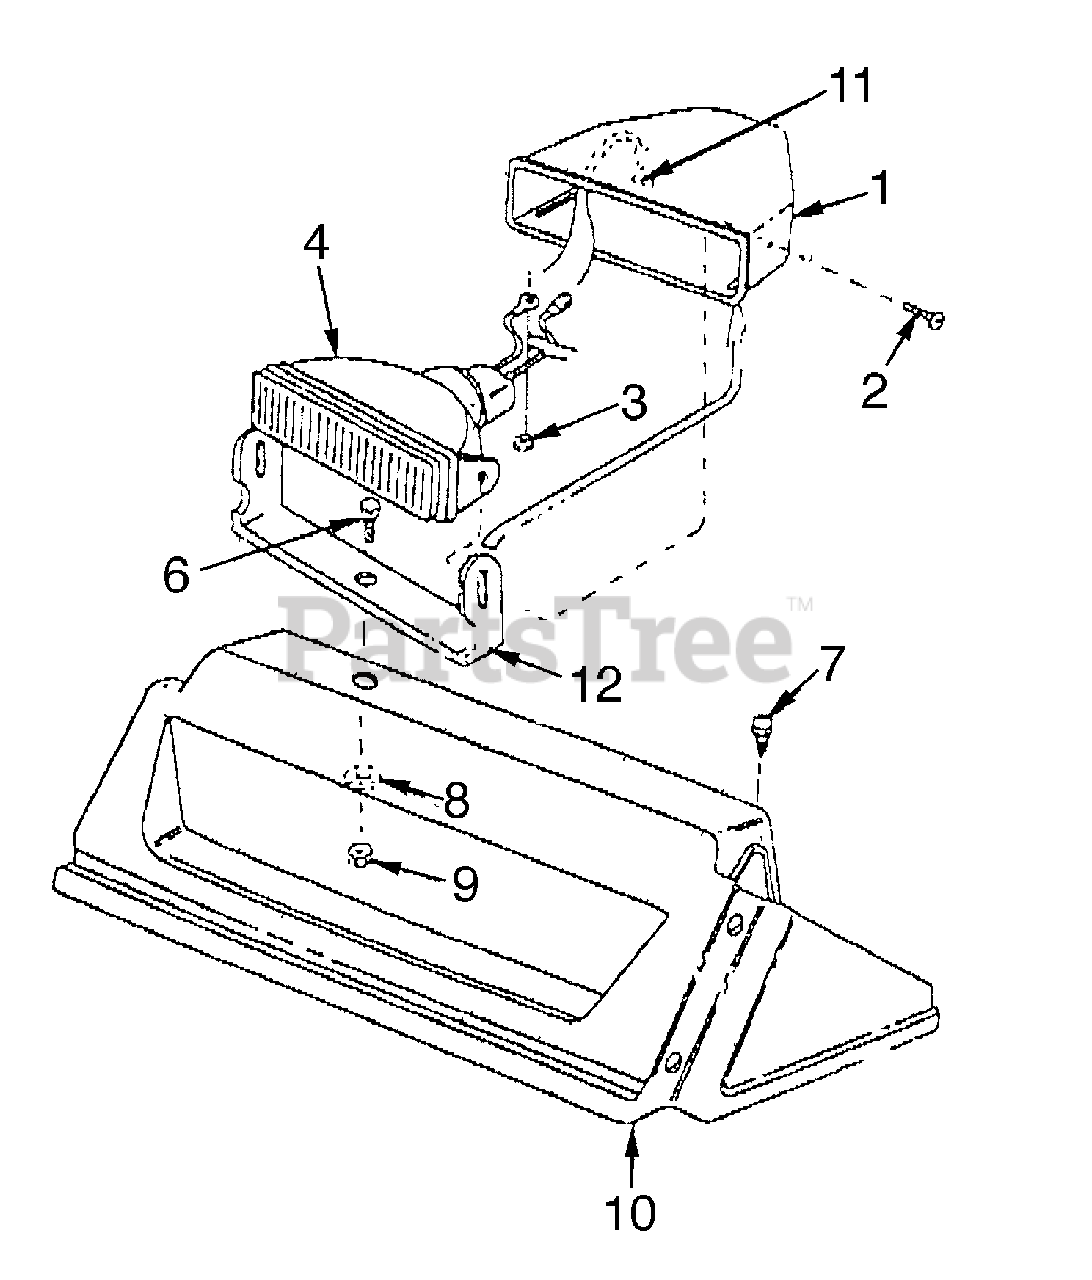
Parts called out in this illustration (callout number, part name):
1	Halogen Lamp Housing
2	Phillips Pan Head Screw M 4 x 16
3	Hex Sems Nut 1/4-20
4	Lamp/Lens Housing Ass'y
6	Carriage Bolt 5/16-18 x .75
7	Pan Head B-Tapp Screw #10
8	Fl-Wash .344 ID x .88 OD
9	Hex Ins L-Nut 5/16-18
10	Handle Panel
11	Grommet .38 ID x .50 OD x 12
12	Lamp Mounting Bracket
